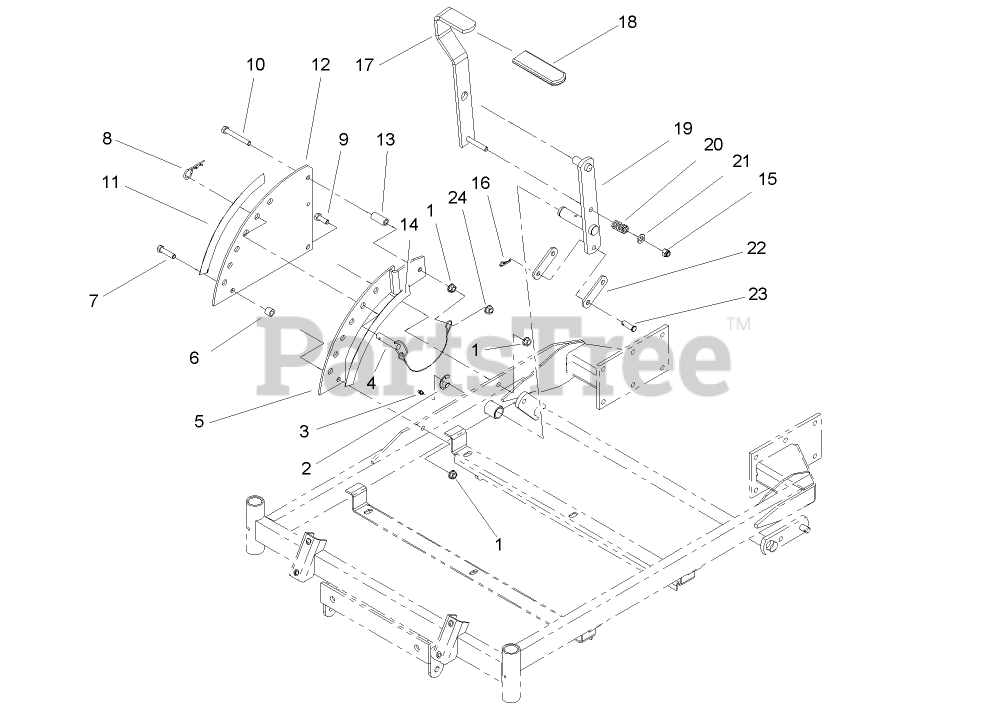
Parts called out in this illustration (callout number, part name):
1	NUT-HHF, WHIZ
2	RING-RETAINING, EXT
3	FITTING-GREASE
4	PIN-HITCH
5	PLATE-LIFT
6	BUSHING-LEVER, LIFT
7	SCREW-HH
8	PIN-COTTER
9	SCREW-HH
10	SCREW-HH
11	DECAL-DECK HEIGHT, OUTER
12	PLATE-DECK LIFT
13	BUSHING-LEVER, LIFT
14	DECAL-DECK HEIGHT, INNER
15	NUT-LOCK, NI
16	PIN-COTTER
17	LEVER-LIFT
18	GRIP-LEVER, LIFT
19	ARM-DECK, LIFT
20	SPRING-COMPRESSION
21	WASHER-FLAT
22	ARM-LIFT, DECK
23	PIN-CLEVIS
24	NUT-HF
